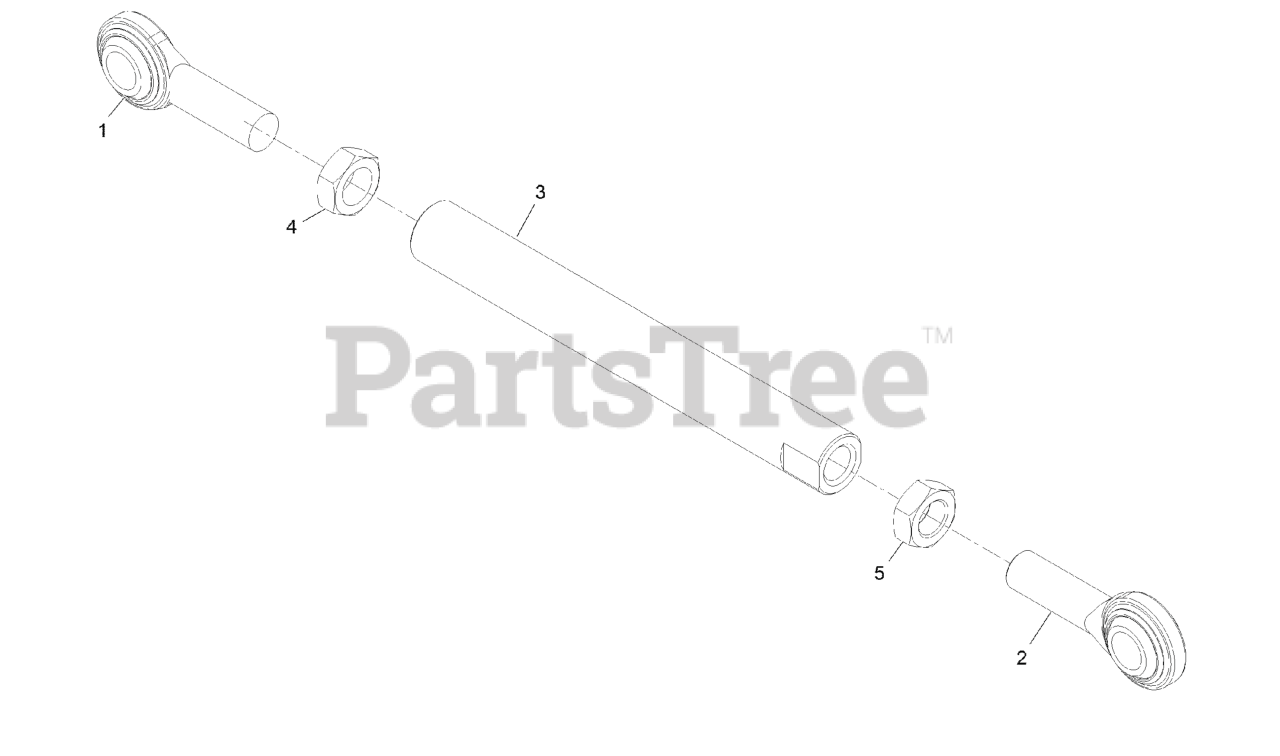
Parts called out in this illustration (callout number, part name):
1	BALLJOINT-SPHERICAL
2	BALLJOINT-SPHERICAL
3	ROD, LIFT
4	NUT-JAM
5	NUT-JAM
